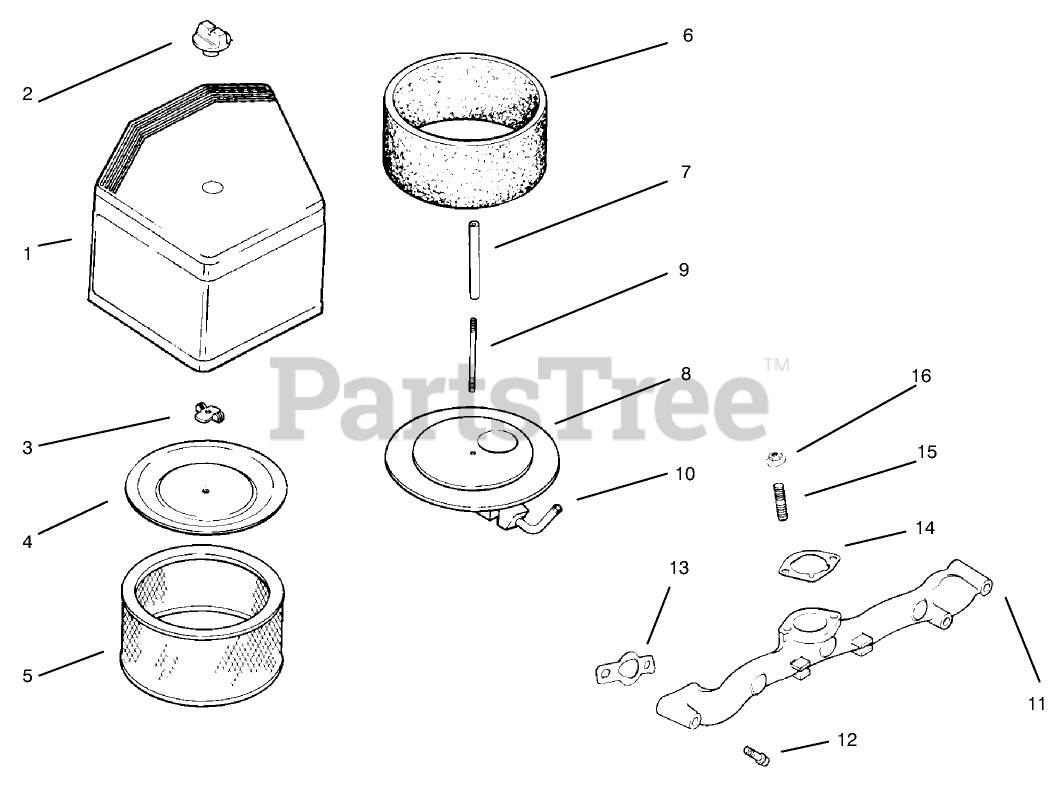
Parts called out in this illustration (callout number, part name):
1	Kit-Air Cleaner Incl. 2
2	Knob-Cover
3	Wingnut
4	Cover-Element
5	Precleaner
6	Element
7	Seal
8	Elbow-Air Cleaner
9	Stud
10	Fitting
11	Manifold-Intake
12	Screw
13	Gasket-Intake, Manifold
14	Gasket-A/C Base
15	Stud
16	Nut
